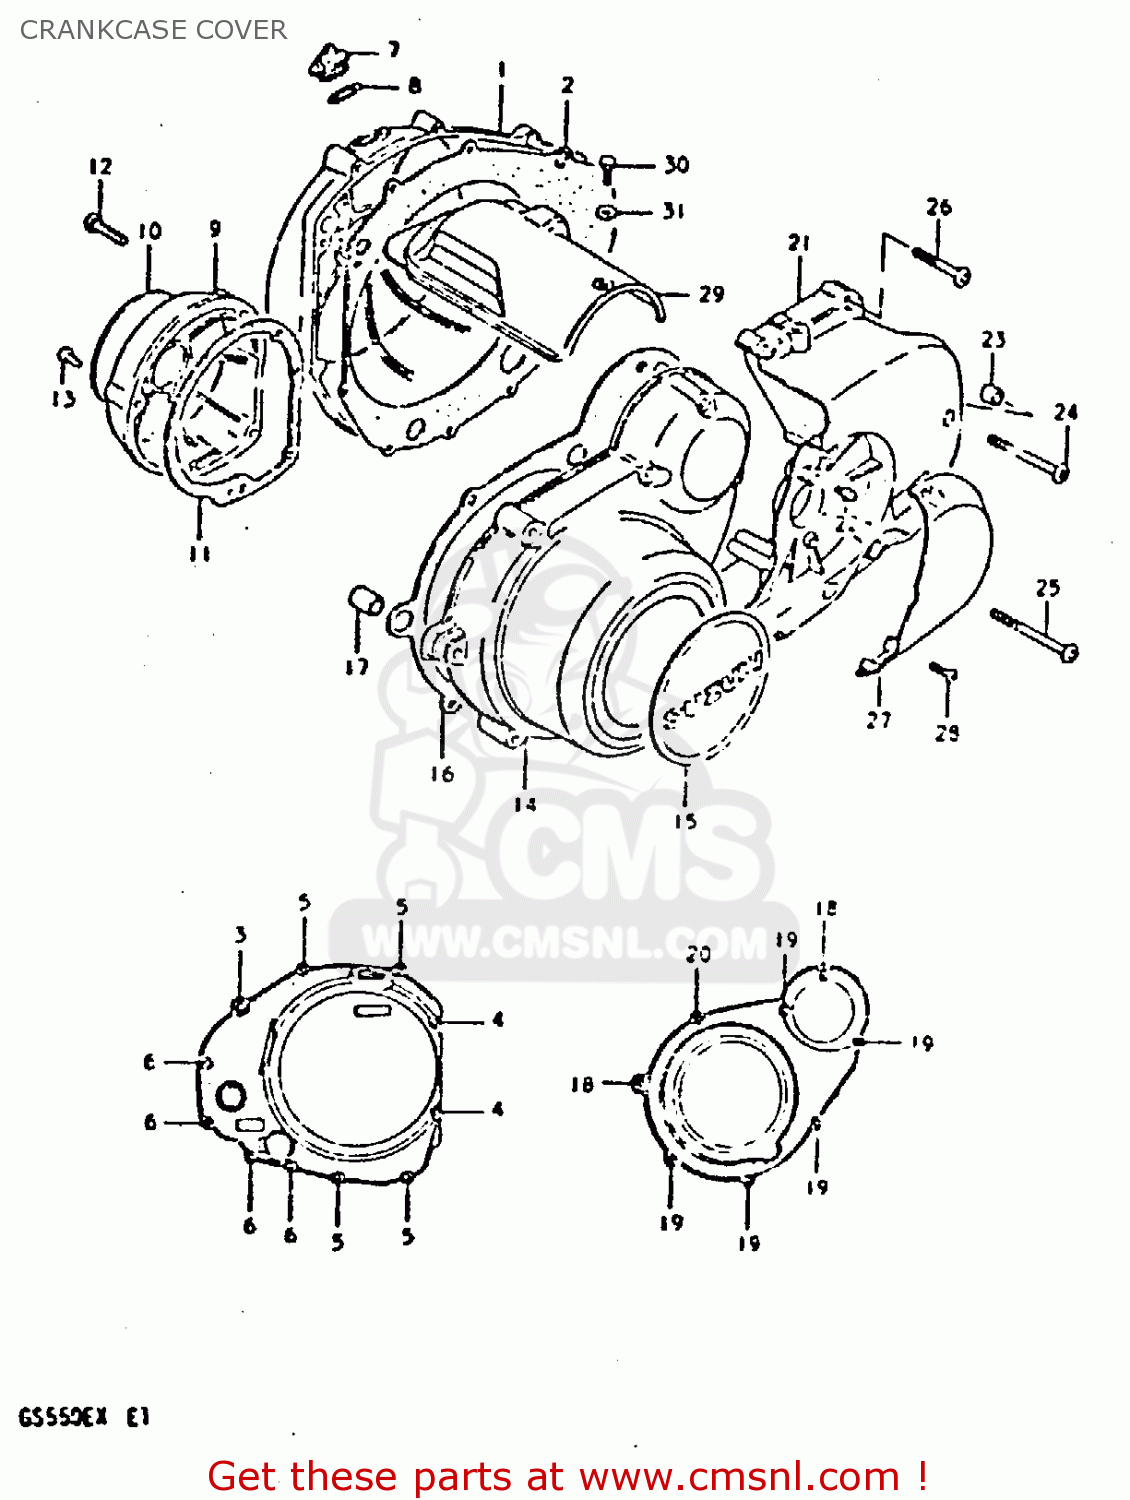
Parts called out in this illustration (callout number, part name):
1	COVER,CLUTCH
2	GASKET,CLUTCH COVER (MCA)
3	SCREW (6X35)
4	SCREW
5	SCREW
6	SCREW
7	PLUG, OIL FILLER
8	O RING(D:2.2,ID:32)
9	COVER,CONTACT BREAKER
10	EMBLEM,CONTACT BREAKER COVER
11	GASKET,CONTACT BREAKER COVER (NAS)
12	SCREW
13	SCREW
14	COVER
15	EMBLEM,MAGNETO COVER
16	GASKET,MAGNETO COVER (MCA)
17	PIN
18	SCREW
19	SCREW
20	SCREW (6X35)
21	CRANKCASE SET
22	NIPPLE
23	PIN
24	SCREW
25	SCREW 6X80
26	SCREW 6X30
27	CAP,CLUTCH RELEASE ADJUST
28	SCREW
29	COVER,STARTER MOTOR
30	BOLT
31	WASHER
